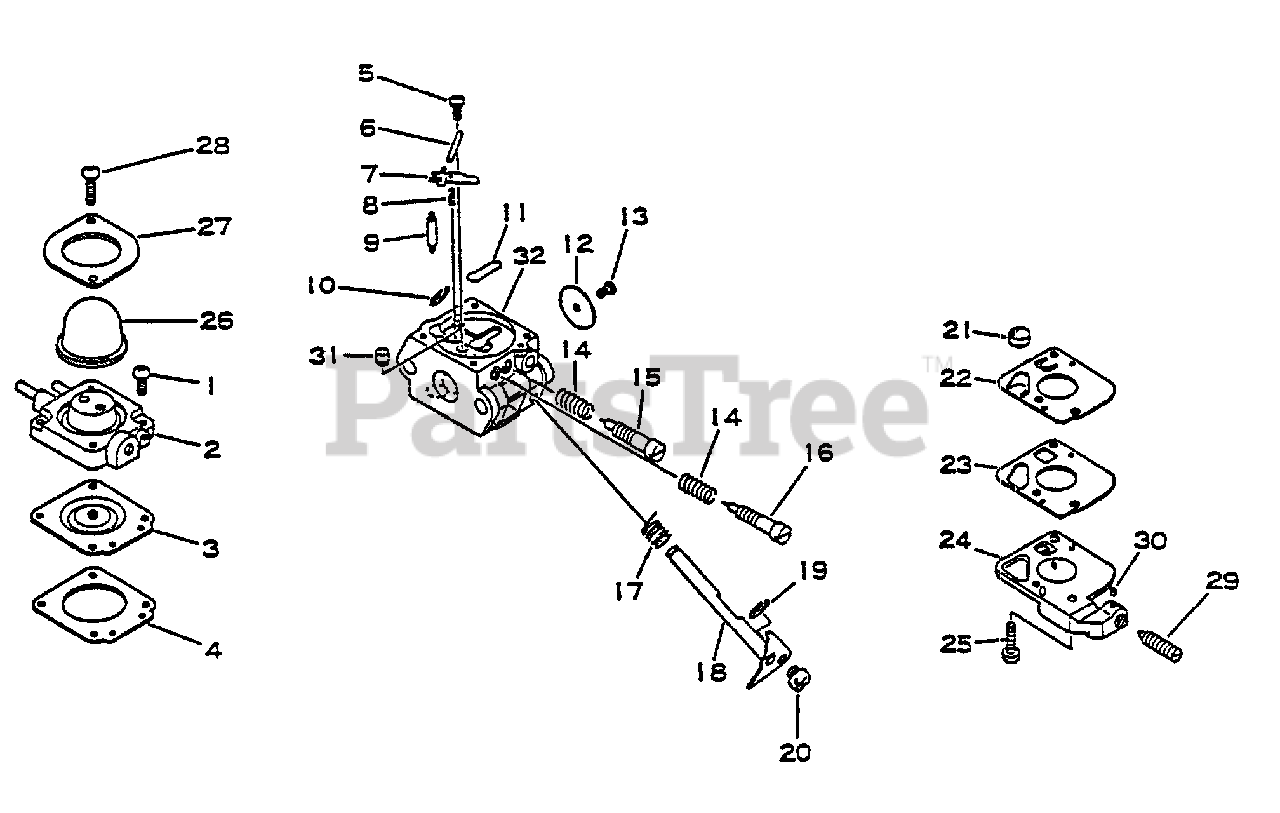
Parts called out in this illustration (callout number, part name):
1	SCREW, PURGE BASE
2	BASE, PURGE
3	DIAPHRAGM
4	GASKET, METERING
5	SCREW
6	PIN
7	LEVER, METERING
8	SPRING
9	VALVE, NEEDLE
10	RING, RETAINING
11	PLUG, WELCH
12	VALVE, THROTTLE
15	NEEDLE - MIXTURE
16	NEEDLE - HIGH SPEED
17	SPRING, RETURN
18	SHAFT, THROTTLE
19	RING, RETAINING
21	STRAINER
22	DIAPHRAGM, PURGE
23	GASKET, PURGE
24	BASE, PURGE
25	SCREW, PUMP COVER
26	BULB, PURGE
27	RETAINER, PURGE BULB
28	SCREW, RETAINER
29	SCREW, IDLE ADJUST
30	PIECE, FRICTION
31	NOZZLE, CHECK VALVE
